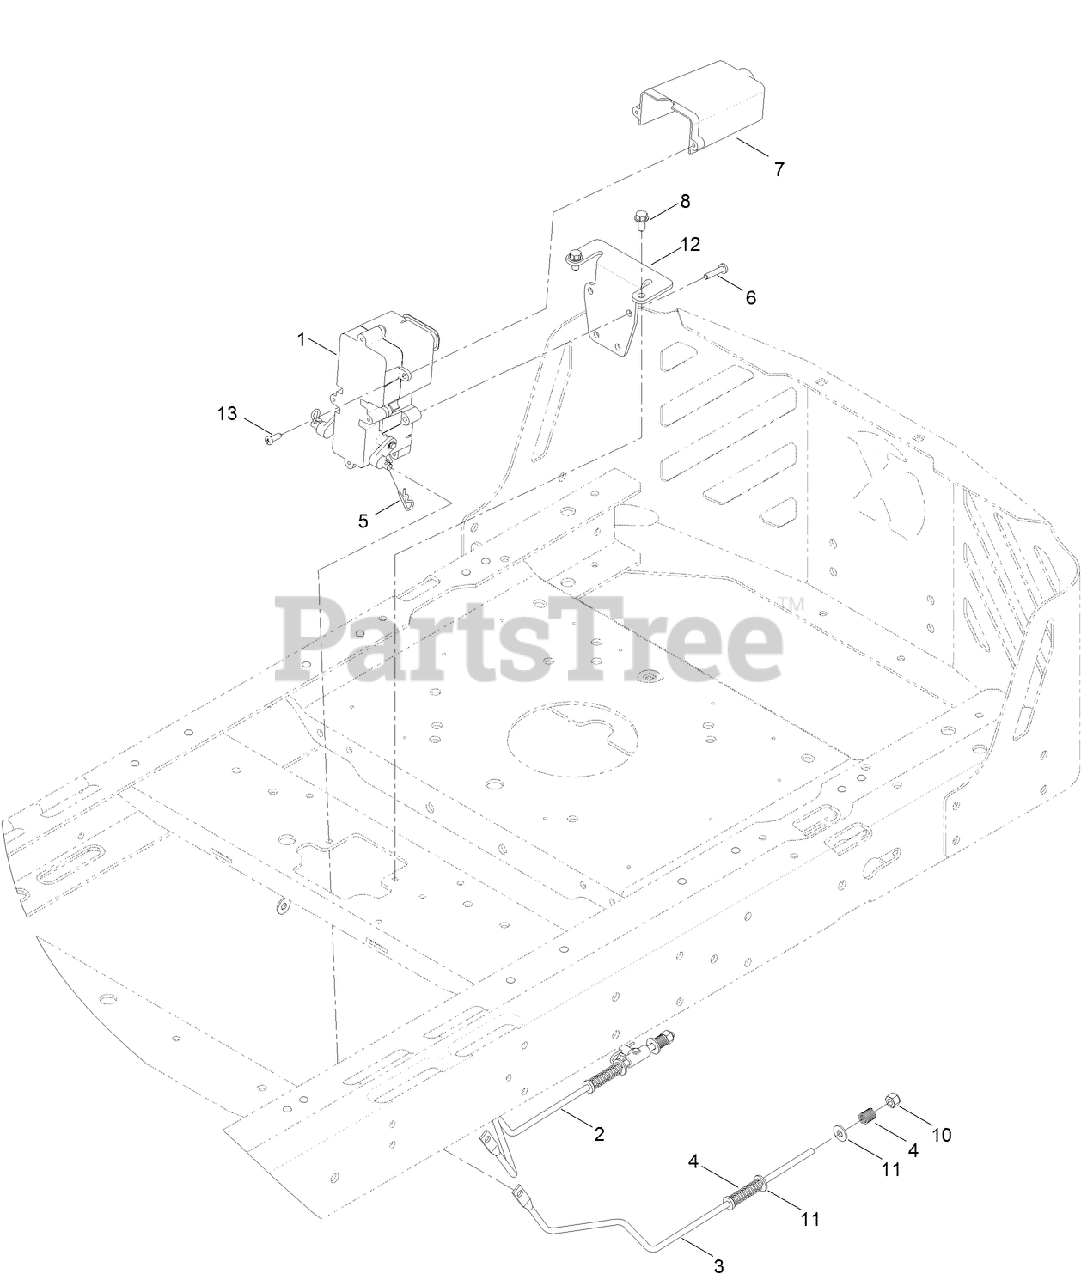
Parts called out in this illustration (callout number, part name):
2	ROD-BRAKE, WIDE (RH)
3	ROD-BRAKE, WIDE (LH)
4	SPRING-COMPRESSION
6	SCREW-PPH
8	SCREW-HWH
10	NUT-LOCK, NI
11	WASHER
12	BRACKET-MOUNT, BRAKE
13	SCREW-PPH
